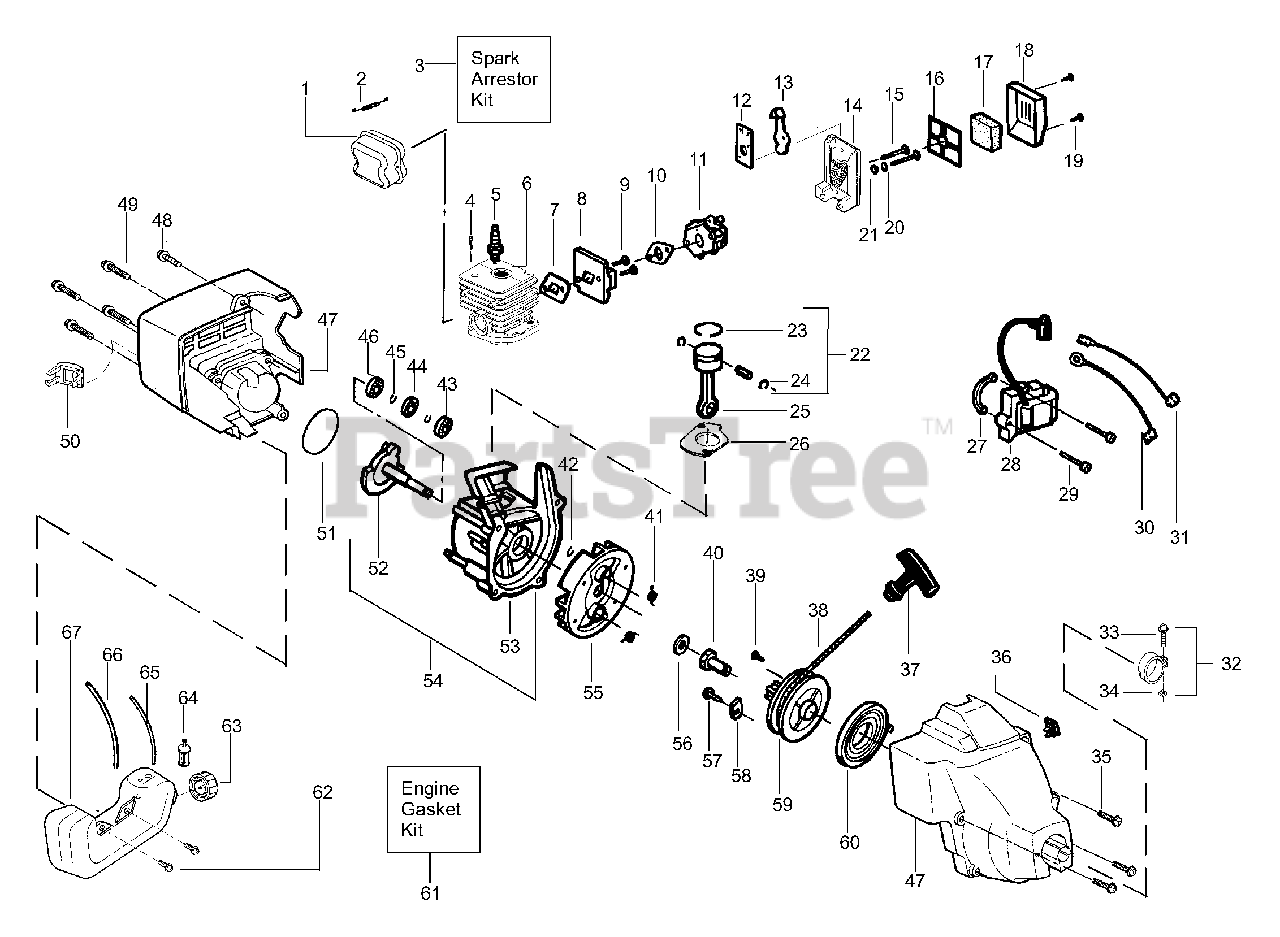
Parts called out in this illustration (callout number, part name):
1	Kit-Muffler
2	Muffler Spring
3	Kit-Spark Arrestor
4	Screw-Cylinder
5	Spark Plug (RC J6Y)
6	Kit-Cylinder
7	Gasket-Cylind./Carb.
8	Kit-Carb. Adaptor
10	Gasket-Carb.
11	Kit-Carburetor Ass'y
12	Plate-Choke Mounting
13	Shutter-Choke
16	Plate-Filter Support
17	Foam-Air Filter
18	Cover-Air Filter
20	Spacer-Choke
22	Kit-Piston
23	Ring-Piston
24	Retainer-Piston Pin
25	Assy-Connecting Rod
26	Gasket-Cylinder
27	Spacer-Module
28	Ignition Module
30	Assy-Ground Wire
31	Assy-Leadwire
32	Assy-Nose Cone Clamp
33	Screw-Nose Cone
34	Nut-Nose Cone
35	Screw
36	Kit-Momentary
37	Starter Handle
38	Kit-Rope
40	Coupling-Drive
41	Starter Dog Spring
42	Retain. Ring-C'shaft
43	Outer Bearing
44	C'case Seal
45	Retainer Ring-C'case
46	Inner Bearing
47	Assy.-Fan Hsg/Shroud
49	Screw
50	Guard-Muffler
51	O--Ring-C'case/Shrd
52	Assy-Crankshaft
53	Assy-Crankcase
54	Assy-C'case & C'shaft
55	Assy-Flywheel
56	Washer-Flat
58	Retainer-Can
59	Kit-Starter Pulley
60	Starter Spring
61	Kit-Engine Gasket
62	Retainer
63	Assy-Fuel Cap
64	Assy-Fuel Pickup
65	Kit-Fuel Line (Small)
66	Kit-Fuel Line (Large)
67	Assy-Fuel Tank
